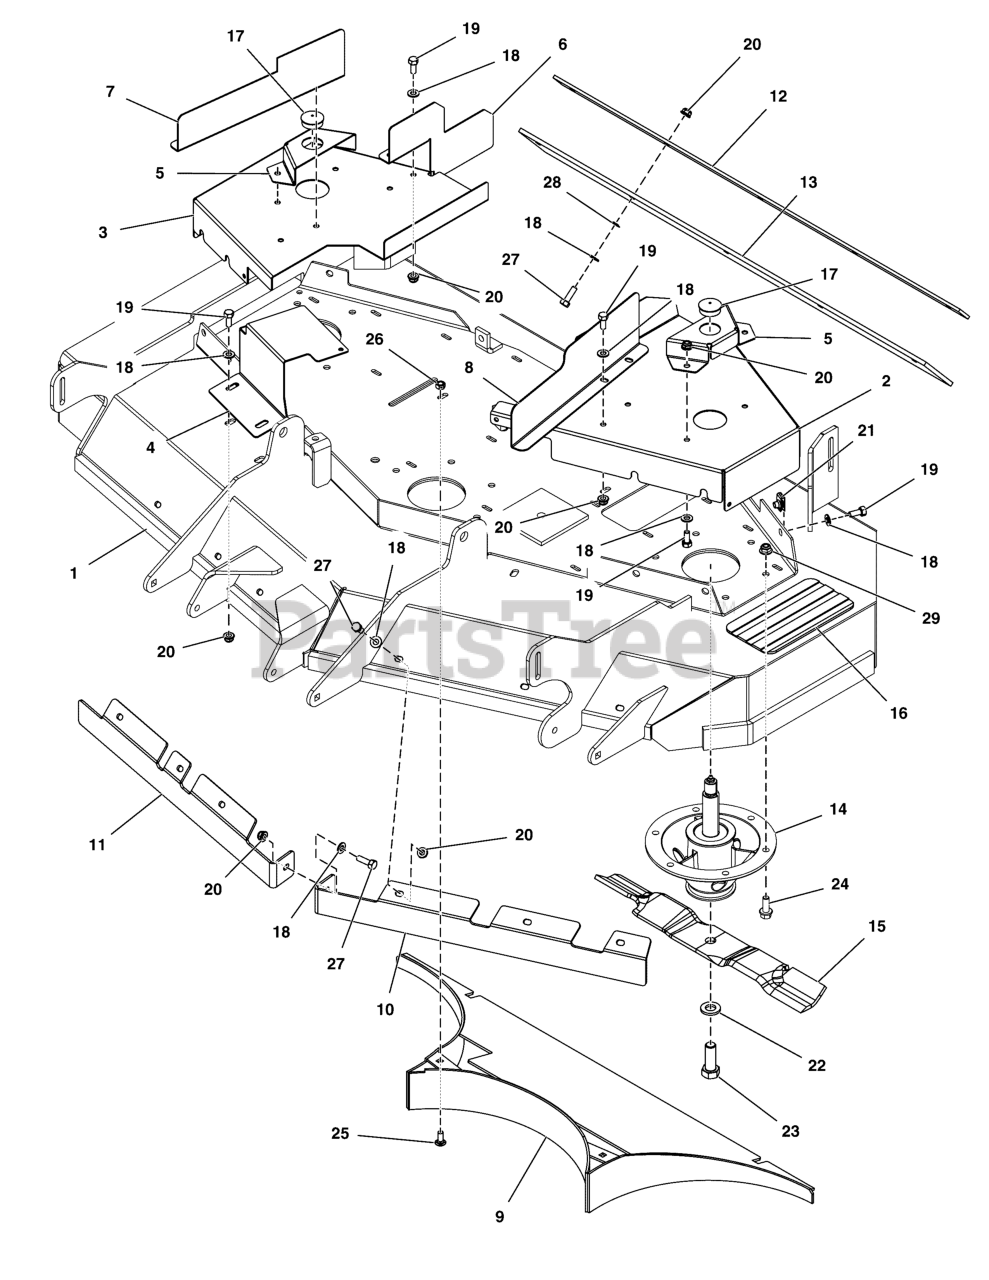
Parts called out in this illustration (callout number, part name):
1	DECK SHELL W/ DECALS, IS2100Z-52RD (5416992B)
2	PLATE, DECK GUARD, LH 52" CE - RED
3	PLATE, DECK GUARD, RH 52" CE - RED
4	GUARD, FRONT CUTTER DECK, 52" CE - RED
5	GUARD, GREASE FITTING, CE - RED
6	PLATE, DECK SHIELD, REAR, 52, RH - RED
7	PLATE, DECK SHIELD, FRONT, 52, RH - RED
8	PLATE, DECK SHIELD, FRONT, 52, LH - RED
9	WELD, REAR BAFFLE, SHRT - BLK
10	BAFFLE, FRONT DISCHARGE LH - RED
11	BAFFLE, FRONT DISCHARGE RH - RED
12	PLATE, FLAP RETAINER, 2000 RD - BLK
13	FLAP, 2000 REAR DISCHARGE
14	SPINDLE ASSM, CAST IRON 8.0-6 BOLT, LS
15	BLADE SET, MULCH, 52 DECK (SET OF 3)
16	SAFETY WALK, 4.00 X 7.50
17	PLUG, PANEL, 1.25 - BLACK
18	WASHER, 5/16" SAE
19	BOLT, 5/16-18 X 3/4 GD5
20	NUT, 5/16-18 HEX NYLOCK FLANGE NUT
21	BODY CLIP, 5/16-18-7GA MATERIAL
22	WASHER, BLADE BOLT, 9/16" F436, CZ
23	BOLT, 5/8-11 X 1-3/4 GD8
24	BOLT, 3/8-16 X 1, FLANGE, GD 5, CZ
25	BOLT, 5/16-18 X 3/4, CARRIAGE, GD5, CZ
26	NUT, 5/16-1/8, HEX, CNTR LK, ZINC PHOS/OIL
27	BOLT, 5/16-18 X 1" GRD5 YZ
28	5/16" PUSH-ON NUT RETAINER, STL, CZ
29	NUT, 3/8 - 16 HEX NYLOCK FLANGE
